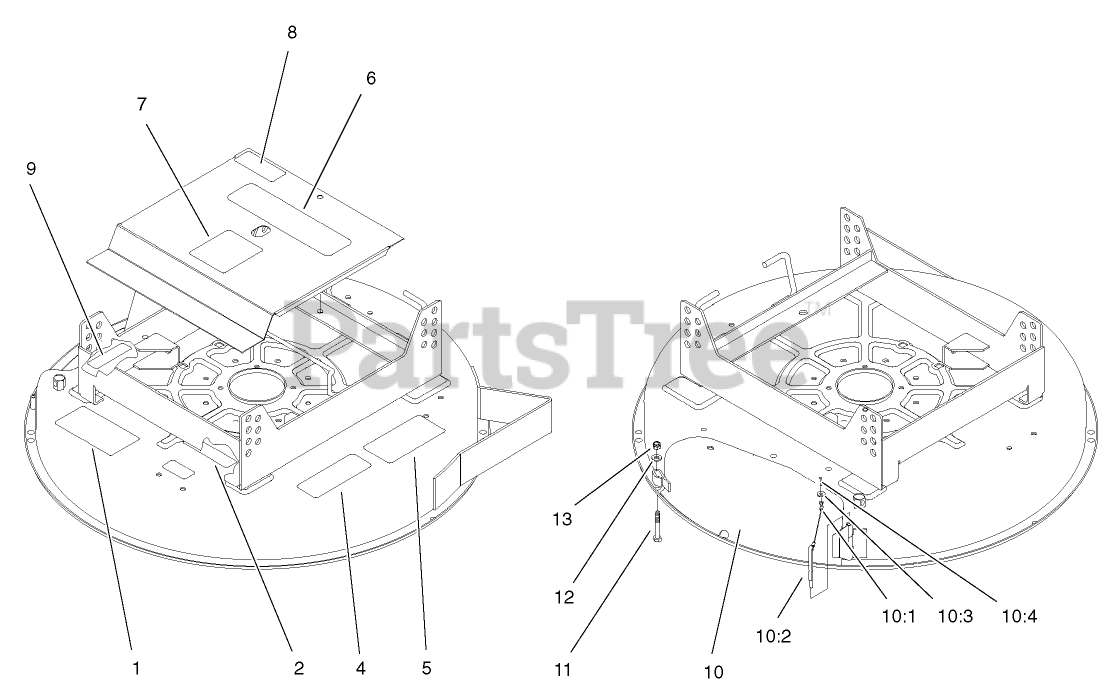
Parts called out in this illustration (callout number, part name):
1	DECAL-DANGER, THROWN OBJECT
2	DECAL-DANGER
4	DECAL-TORQUE
5	DECAL-HOC
6	DECAL-PROLINE
7	DECAL
8	DECAL-HOT
9	DECAL-DANGER
10	MULCHER COVER ASM
10:1	LANYARD
10:2	PIN-LOCKING, CHUTE
10:3	WASHER-PLAIN
10:4	RIVET-BLIND
11	SCREW-HH
12	WASHER-PLAIN
13	NUT-LOCK, NI
